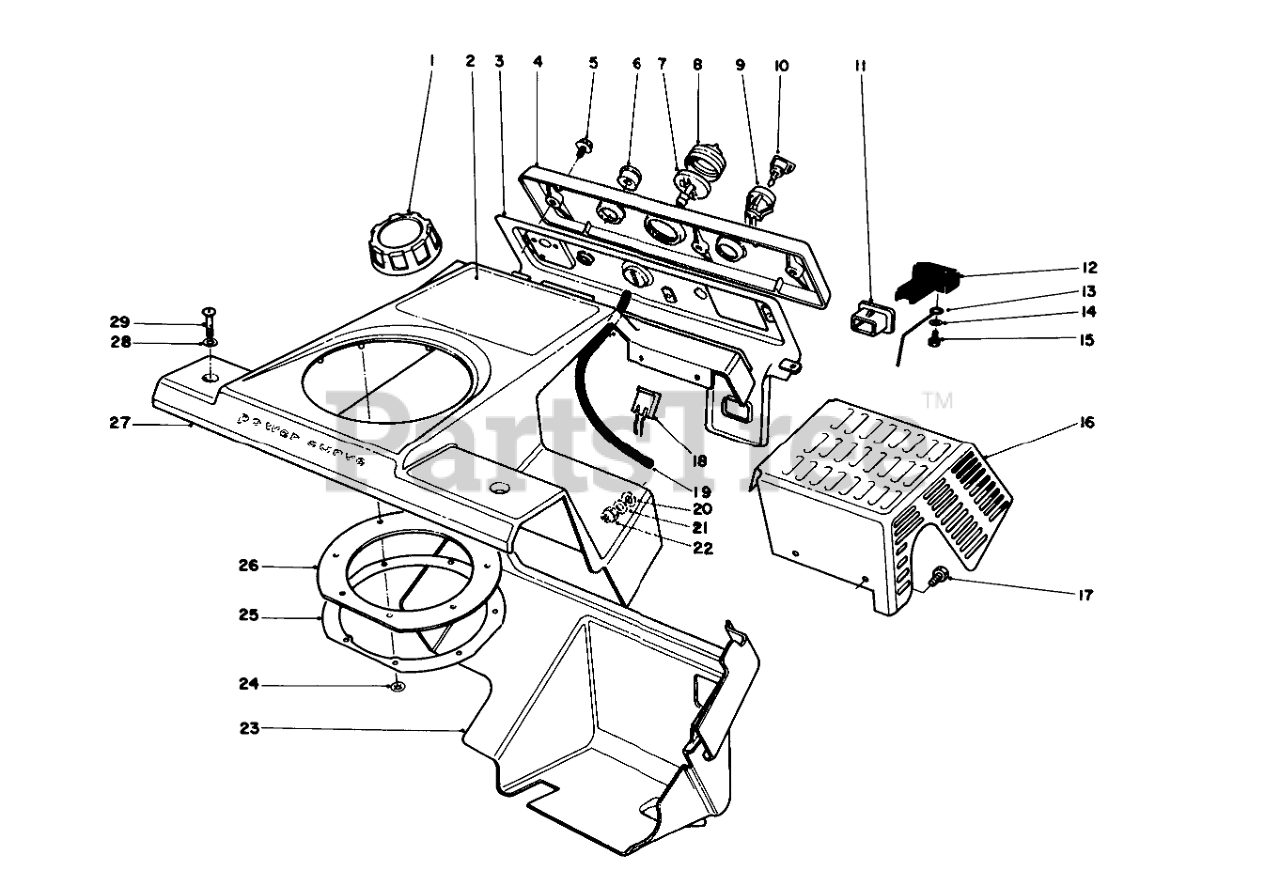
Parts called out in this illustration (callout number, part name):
1	CAP-FUEL ASM
2	DECAL - CCR 2000
3	Control Panel Assembly (Incl. Ref. #6-8 & 11)
4	CONTROL NAMEPLATE
5	SCREW-HWHTF
6	GUIDE-ROPE, STARTER
7	BODY-PRIMER
8	BULB-PRIMER
9	SWITCH
10	KEY-IGNITION
11	FITTING
12	CONTROL-CHOKE
13	Unkage-Choke
14	WASHER-PLAIN
15	SCREW-PPH
16	Wa-Shield
17	SCREW-SHH
18	CONNECTOR-BODY
19	PRIMER HOSE
20	WASHER
21	WASHER-FLAT
22	NUT-LOCK, NI
23	Shroud-Lower
24	PALNUT
25	Retainer-Chute Seal
26	SEAL-CHUTE
27	Upper Shroud Assembly (Incl. Ref. #2 & 24-26)
28	WASHER-FLAT
29	SCREW-PPH
